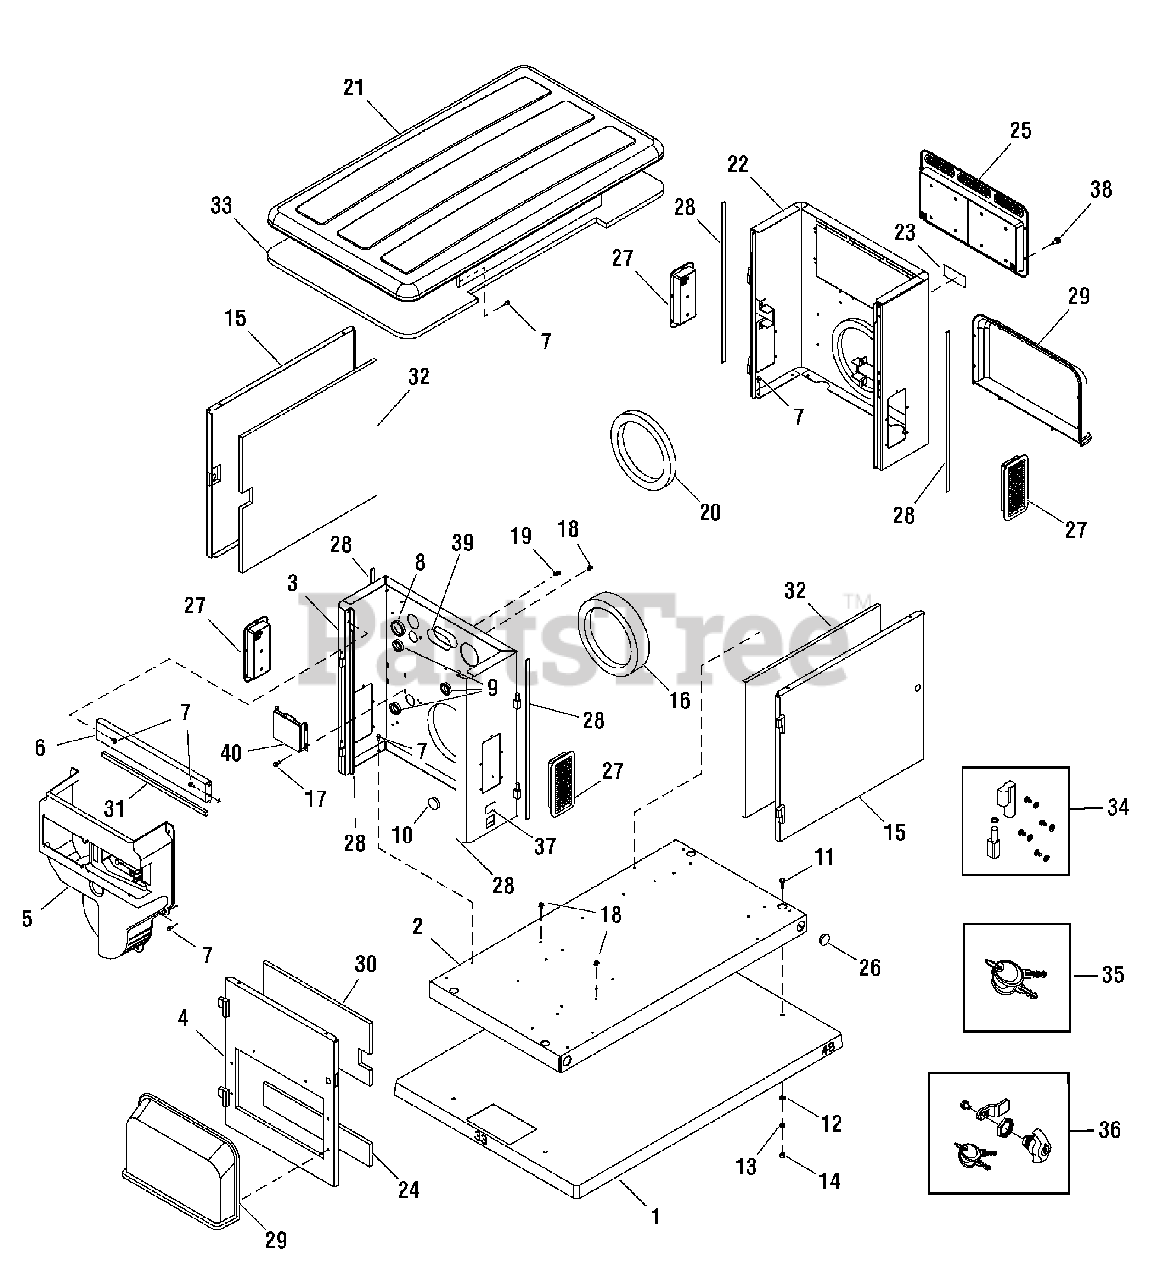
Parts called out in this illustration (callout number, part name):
2	BASE
3	BULKHEAD ASSEMBLY, Engine
6	SUPPORT RAIL ASSEMBLY
7	BOLT
11	* CAPSCREW, Hex Head, 3/8-16 x 1
12	* WASHER, Flat, 3/8 - M10
13	* WASHER, Lock, 3/8
14	* NUT, 3/8-16
16	SEAL, Foam
20	SEAL, Foam
22	BULKHEAD ASSEMBLY, Alternator
29	COVER, Air Intake
40	REGULATOR, Voltage
